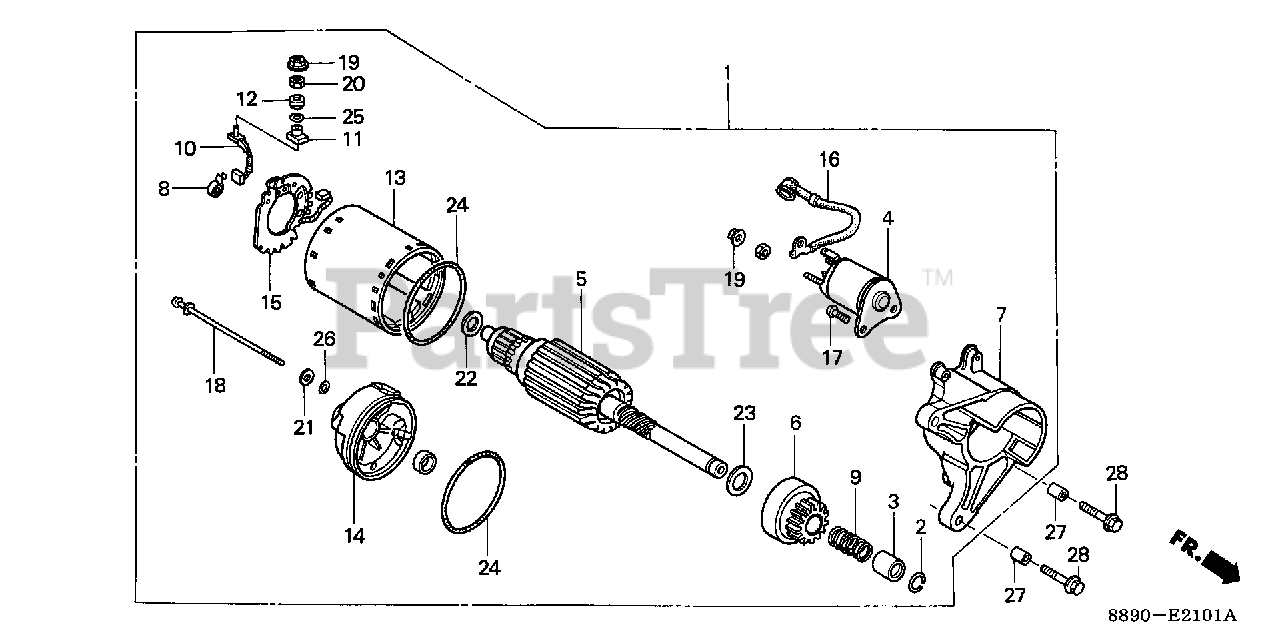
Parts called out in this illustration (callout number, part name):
1	STARTER MOTOR ASSY.
2	RING, SNAP
3	COLLAR, CLUTCH STOP
4	CONTACTOR ASSY.
5	ARMATURE
6	CLUTCH ASSY., OVERRUNNING
7	HOUSING, DRIVE SIDE
8	SPRING, BRUSH
9	SPRING
10	BRUSH
11	BUSH, INSULATION (NOT AVAILABLE)
11	BUSH, INSULATION
12	BUSH, INSULATION (NOT AVAILABLE)
12	BUSH, INSULATION
13	YOKE (NOT AVAILABLE)
13	YOKE
14	FRAME, STARTER END
15	PLATE, BRUSH HOLDER
16	WIRE, WATER COVER (NOT AVAILABLE)
16	WIRE, WATER COVER
17	SCREW-WASHER (5X14)
18	BOLT, THROUGH (NOT AVAILABLE)
18	BOLT, THROUGH
19	NUT
20	NUT
21	WASHER, STEEL PLATE (NOT AVAILABLE)
22	WASHER
23	WASHER
24	O-RING
25	O-RING
26	O-RING
27	PIN, DOWEL (10X16)
28	BOLT, FLANGE (8X35)
